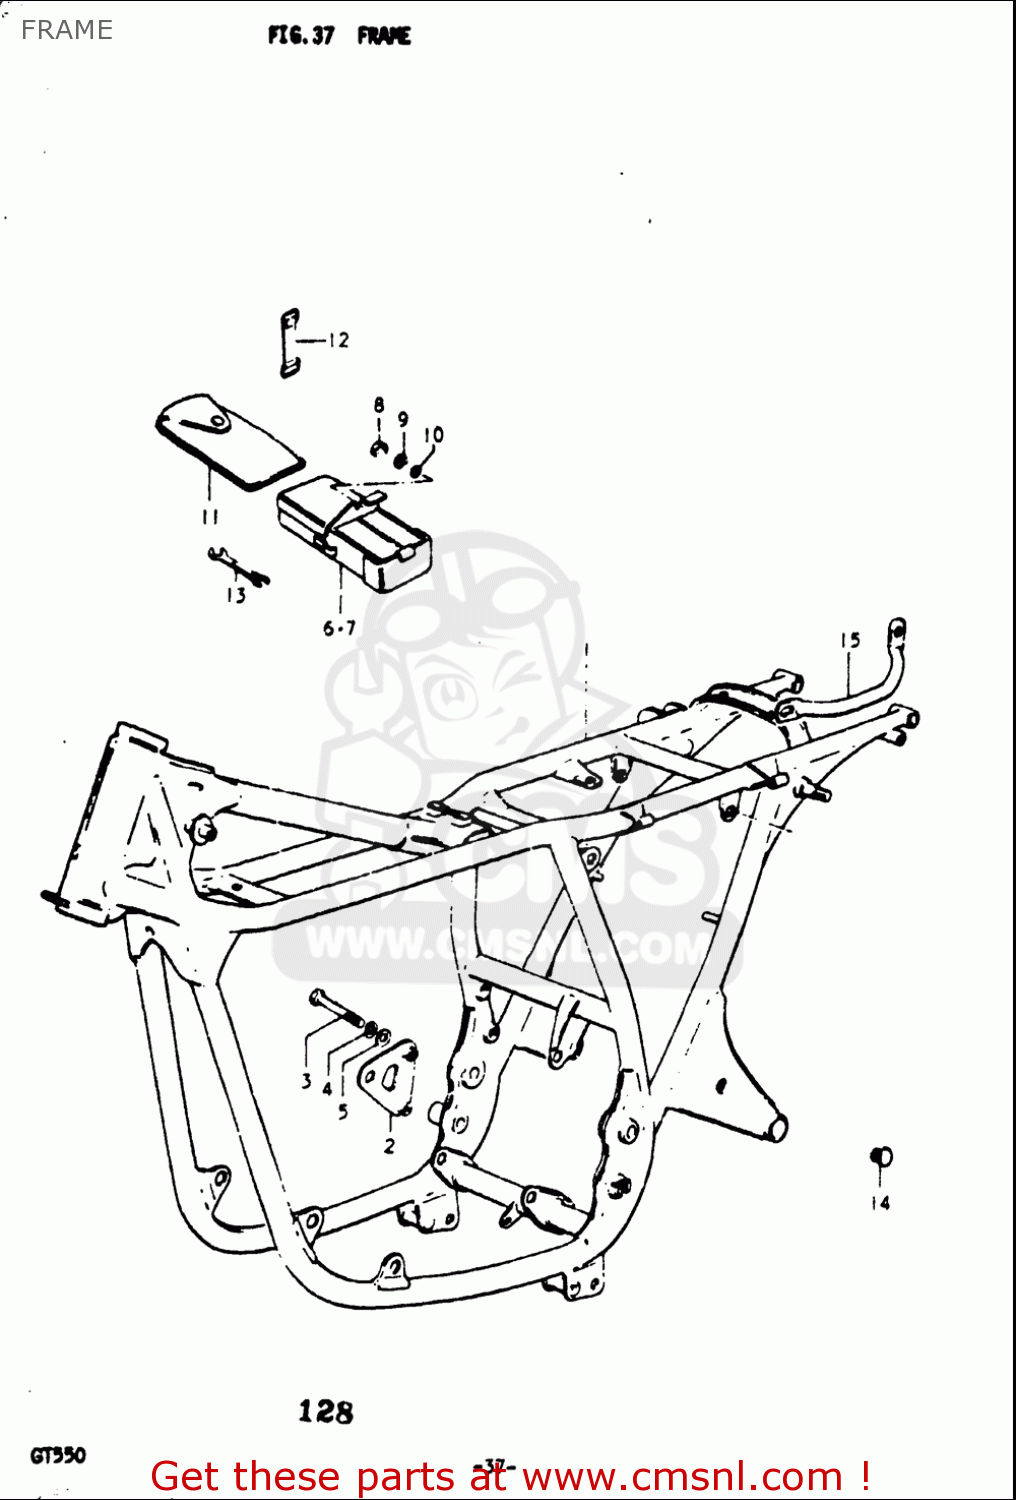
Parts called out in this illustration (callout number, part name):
3	BOLT
4	WASHER,LOCK
5	WASHER
8	NUT
9	WASHER,LOCK
10	WASHER
11	TOOL ASSY
12	BAND
14	CAP(OD:14)
